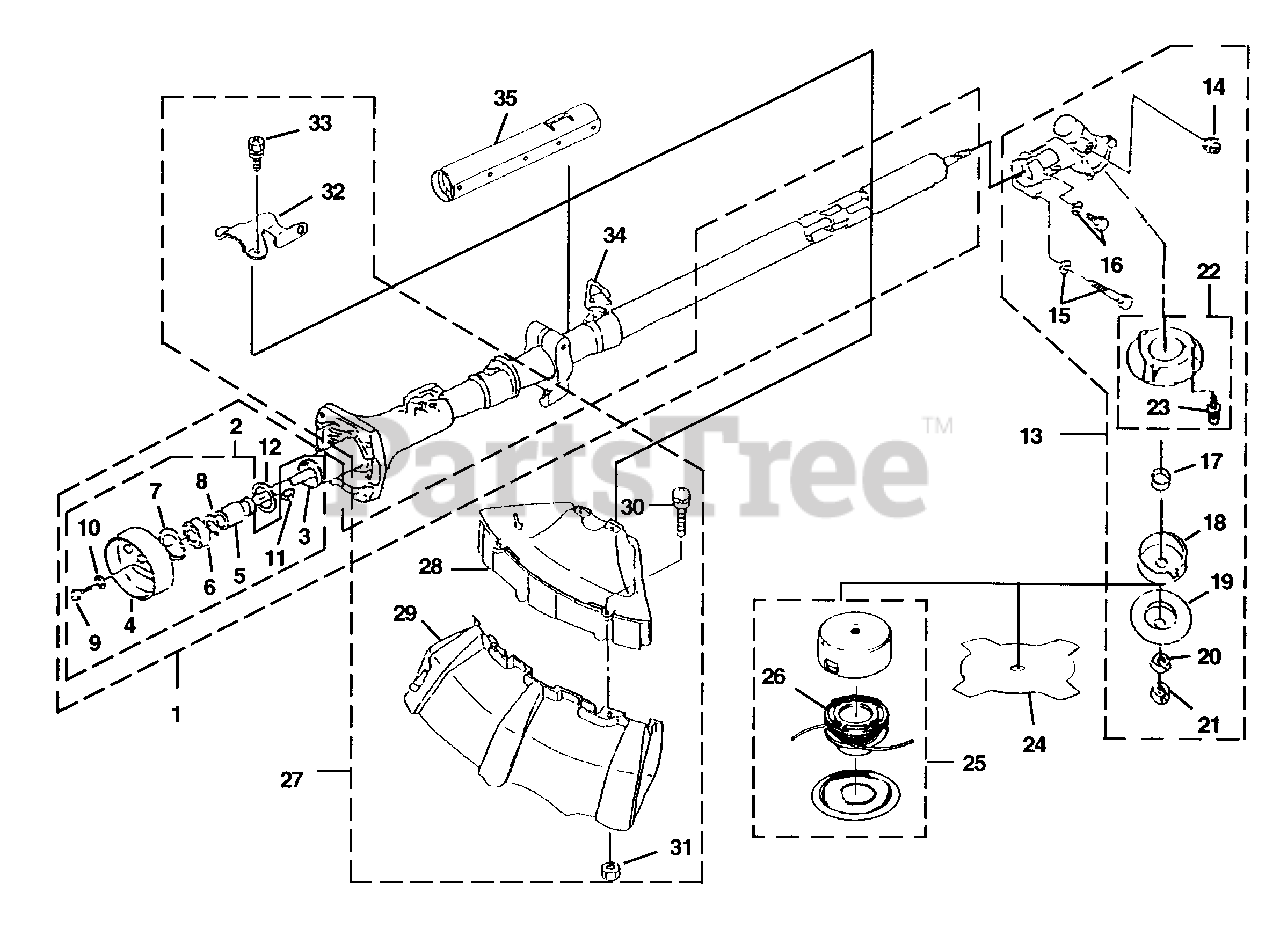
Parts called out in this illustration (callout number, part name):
1	DRIVESHAFT HSG
2	DRIVESHAFT ASSY
3	DRIVESHAFT
4	CLUTCH DRUM
6	BEARING, BALL
7	SNAPPING - Inner
8	SNAPPING - Outer
11	SNAPPING - Outer
13	GEARHEAD ASSEMBLY
14	BOLT-Grease
15	BOLT (M6 X 32)
16	BOLT(M6 X 14)
18	WASHER - Flange
19	WASHER - Clamp
21	NUT
22	GRASS GUARD
23	SCREW-Socket Hd
24	BLADE - Cutter
25	STRING HEAD ASSY
26	SPOOL & STRING
27	PROTECTOR ASSY
28	PROTECTOR COMP
29	PROTECTOR COMP
30	SCREW ASSEMBLY
31	NUT
32	CLAMP, PROTECTOR
33	BOLT ASSEMBLY, CROSSRECESS
34	HANGER ASSEMBLY
